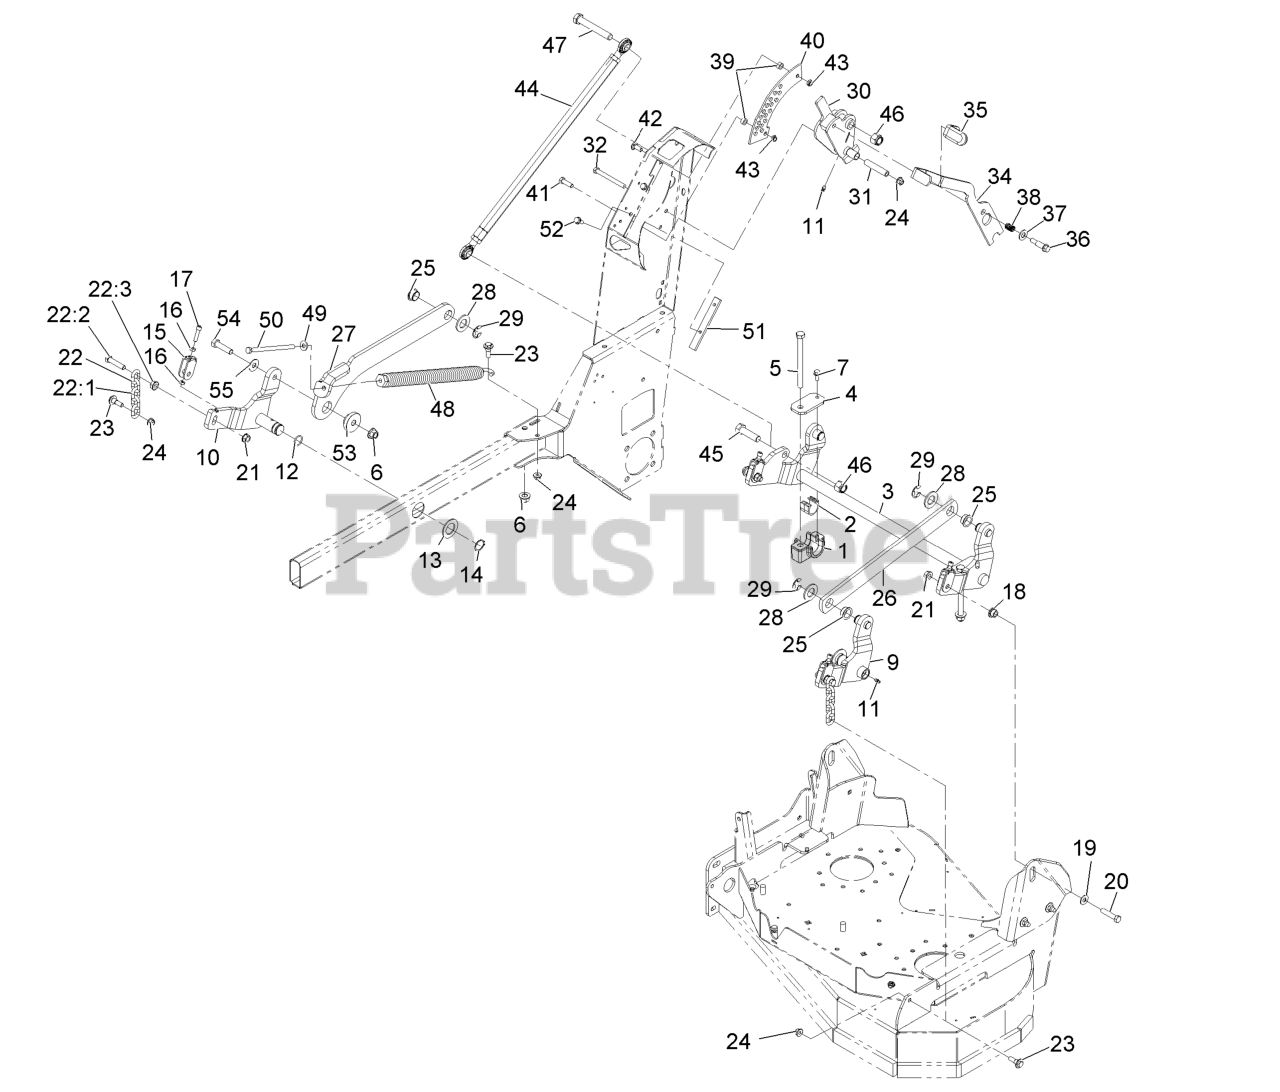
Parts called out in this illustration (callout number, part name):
1	SUPPORT-BEARING
2	BEARING-CROSS SHAFT, FRON
3	REAR CROSSSHAFT ASM
4	COVER-BEARING SUPPORT
5	SCREW-HH
6	Nut-Lock 1/2-13
7	SCREW-HHF
9	DECKLIFT ARM ASM-LH
10	DECKLIFT ARM ASM-RH
11	FITTING-GREASE
12	O RING
14	RING-RETAINING
15	YOKE-ADJUST, DECK
16	NUT-JAM
17	SCREW-HSH
18	BUSHING-FLANGED
19	WASHER-FLAT
20	SCREW-HH
22	DECK LIFT CHAIN ASM
22:1	CHAIN-LIFT, DECK
22:2	SCREW-HH
23	SCREW-SHOULDER, HHF
24	NUT-HF, NI
25	BEARING-FLANGE
26	LINK-DECKLIFT, LH
27	LINK-DECKLIFT, RH
28	WASHER-FLAT
29	RING-RETAINING, EXT
31	BEARING-HOC PIVOT
32	SCREW-HH
34	LEVER-HOC
35	GRIP-LEVER
36	SCREW-SHOULDER
37	WASHER-FLAT
39	SPACER
40	BRACKET-HOC
41	SCREW-HH
42	SCREW-CARR
44	HOC LINK ASM
45	SCREW-HH
46	NUT-LOCK, NI
47	SCREW-HH
48	SPRING-EXTENSION
49	WASHER-BELLEVILLE
50	BOLT-TAP, HH
51	SKID-HANDLE, LIFT
52	SCREW-THD ROLL, HWH
53	BUSHING-FLANGED
54	SCREW-HH
55	WASHER-FLAT
